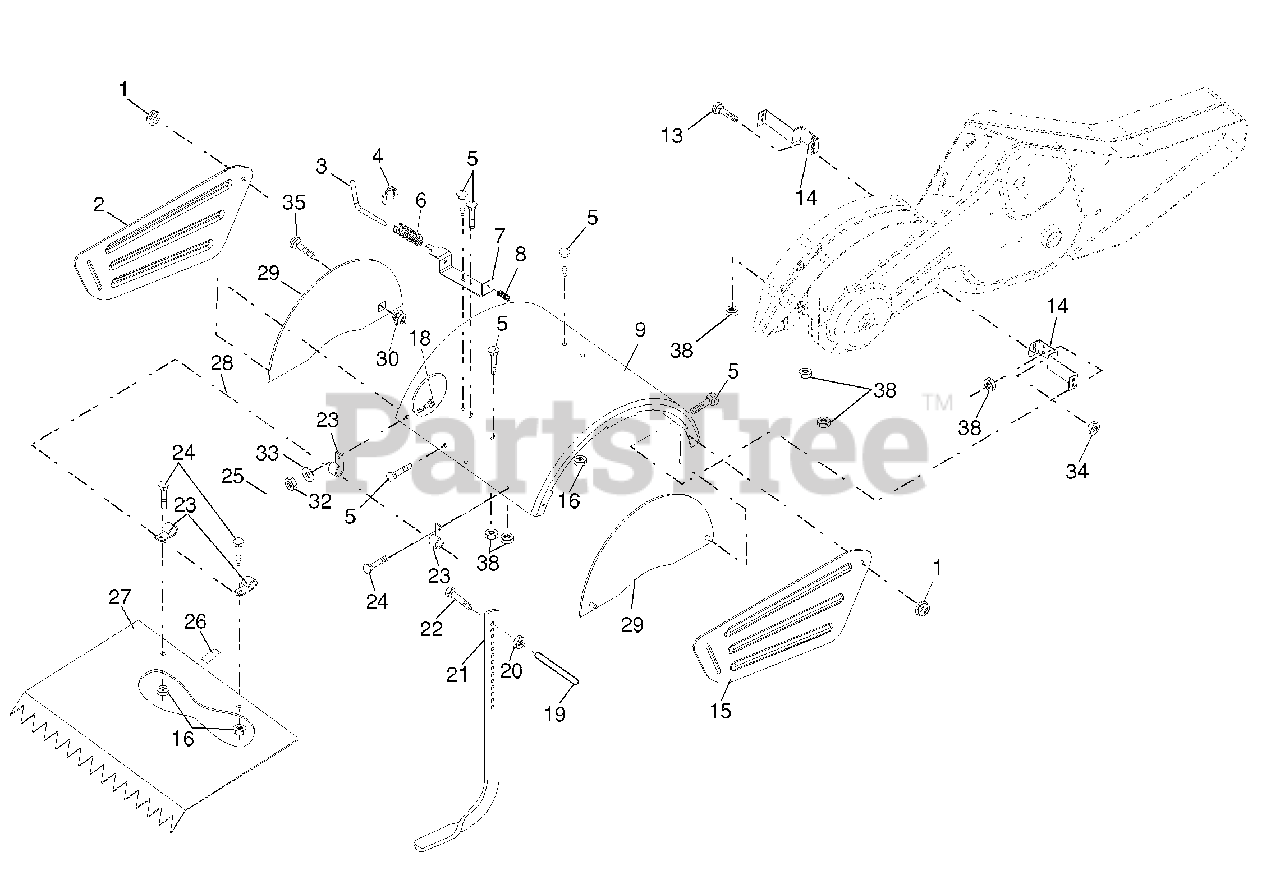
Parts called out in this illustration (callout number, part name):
1	Nut, Lock Hex Flange 5/16-18
2	Shield, Side, Outer L. H.
3	Pin, Stake, Depth
4	Ring, Klip
5	Bolt, Rdhd Sqnk 5/16-18 x 3/4
7	Bracket, Latch
8	Spring, Depth Stake
9	Shield, Tine
13	Bolt, Carriage 5/16-18 x 1-1/4
14	Bracket, Shield Tine
15	Shield, Side, Outer R.H.
16	Nut, Hex Flange 1/4-20 unc
18	Bolt, Carriage 1/4-20 x 1-1/4 Gr.
20	Nut, Hex 3/8-16
21	Stake, Depth
22	Bolt, Hex 3/8-16 x 2
24	Bolt, Carriage 1/4-20 x 1/2 Gr. 5
25	Cap, Vinyl
26	Pad, Idler
27	Shield, Leveling
28	Pin, Hinge
29	Shield, Side
30	Nut Lock Hex Flange
32	Nut Fin Hex 1/4-20 unc
33	Washer Lock Hvy Helical 1/4
34	Locknut, Hex 5/16-18
38	Nut, Keps Hex 5/16-18 unc
